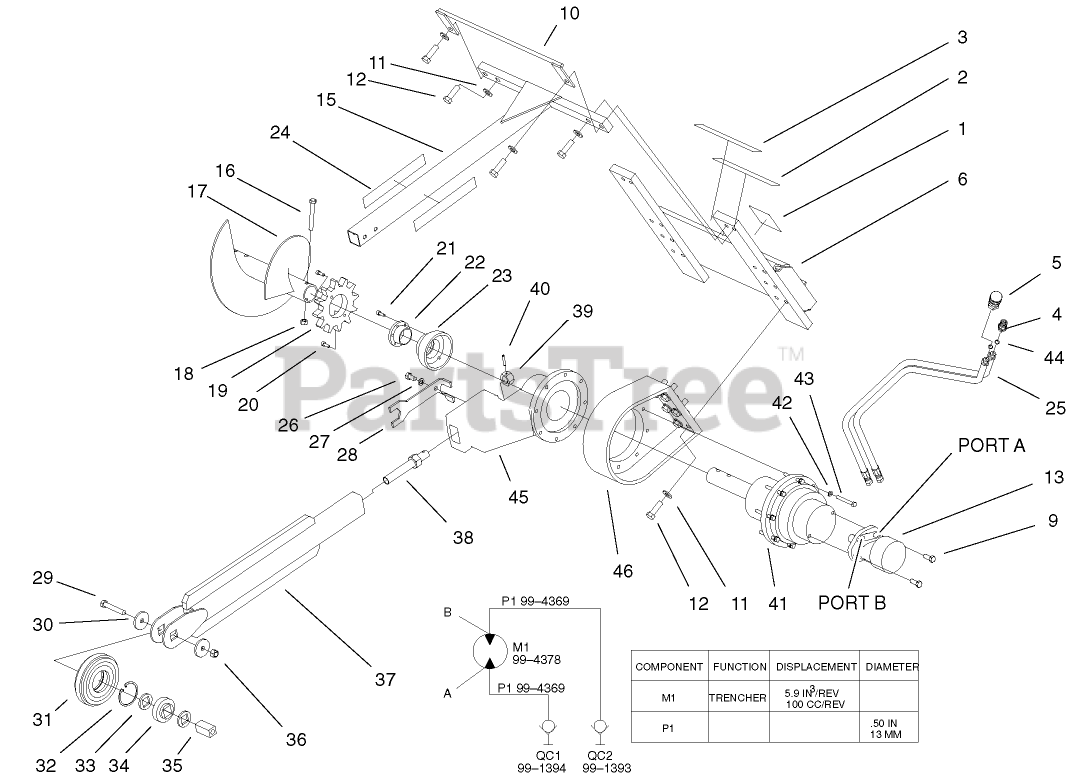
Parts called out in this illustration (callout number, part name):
1	DECAL-ATTACHMENT, DINGO
2	DECAL-DANGER
3	DECAL-DANGER
4	QUICK COUPLER - MALE
5	QUICK COUPLER-FEMALE
6	Frame Assembly (Incl. Ref. #2 & 3)
9	SCREW-HH, LH
10	HOSE GUIDE ASM
11	WASHER-FLAT
12	SCREW-HH
13	Motor-Hydraulic (Incl. Ref. #14
15	Safety Rail ASM (Incl. Ref. #24)
16	SCREW-HH
17	AUGER
18	NUT-LOCK, NI
19	Sprocket
20	SCREW-HSH
21	SCREW-HSH
22	LOCK-TAPER
23	PROTECTOR-SEAL
24	DECAL-DANGER
25	Hose-Hydraulic (Incl. Ref. #44)
26	SCREW-HH
27	WASHER-LOCK
28	SPANNER
29	SCREW-HH
30	WASHER-ROLLER
31	ROLLER-NOSE
32	RING-INT
33	SPACER-ROLLER
34	BEARING-SHAFT, SQUARE
35	PIN-ROLLER
36	NUT-LOCK
37	BOOM ASM
38	Adj Screw ASM (Incl. Ref. #39-40)
39	NUT-HEX
40	PIN-ROLL
41	Gearbox ASM (Incl. Ref. #47-49)
42	WASHER-LOCK
43	SCREW-HH
44	O-RING
45	MOUNT-BOOM
46	MOUNT-DRIVE, PLANETARY
